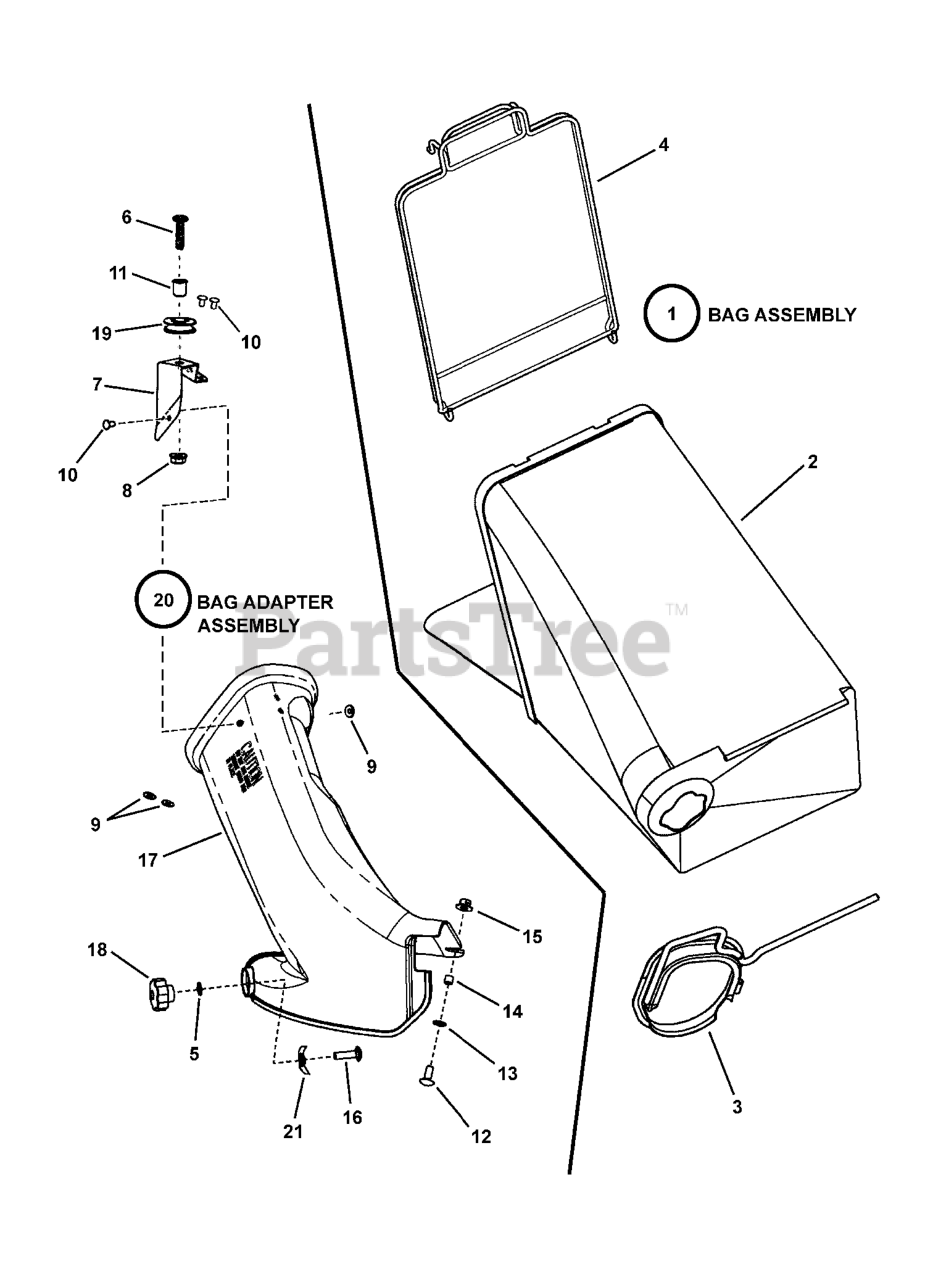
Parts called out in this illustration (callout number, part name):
1	BAG ASSEMBLY, (Door) No Graphics
2	GRASS BAG, (Door) No Graphics
3	CONNECTOR, Bag (weldment)
4	ASSEMBLY, Bag Wire (12") 21S
5	WASHER, 5/16 Internal/External Lock
6	SCREW, 5/16-18 x 1-1/4" Pan Head Self-Tap
7	BRACKET, Rope Guide
8	NUT, 5/16-18 Hex Flange Lock, GR 5
9	WASHER, .497 x .030 Flat
10	RIVET, 3/16 x .344
11	BUSHING, .381 x .625 x .62 Flange
12	BOLT, 5/16-18 x 3/4" Round Head Short Square Neck Carriage, GR 5
13	BOLT RETAINER, 5/16- Black
14	SPACER, .316 x .375 x .300/.310
15	NUT, 5/16-18- Large Flange Hex Center Lock, Black
16	SCREW, 5/16-18 x 5/5" Cross Recess Pan Head
17	ADAPTER, Bag
18	KNOB, Fluted (5/16-18 Thread x .633)
19	PULLEY, Nylon
20	ASSEMBLY, Bag Adapter
21	NUT, 5/16-18 Speed
